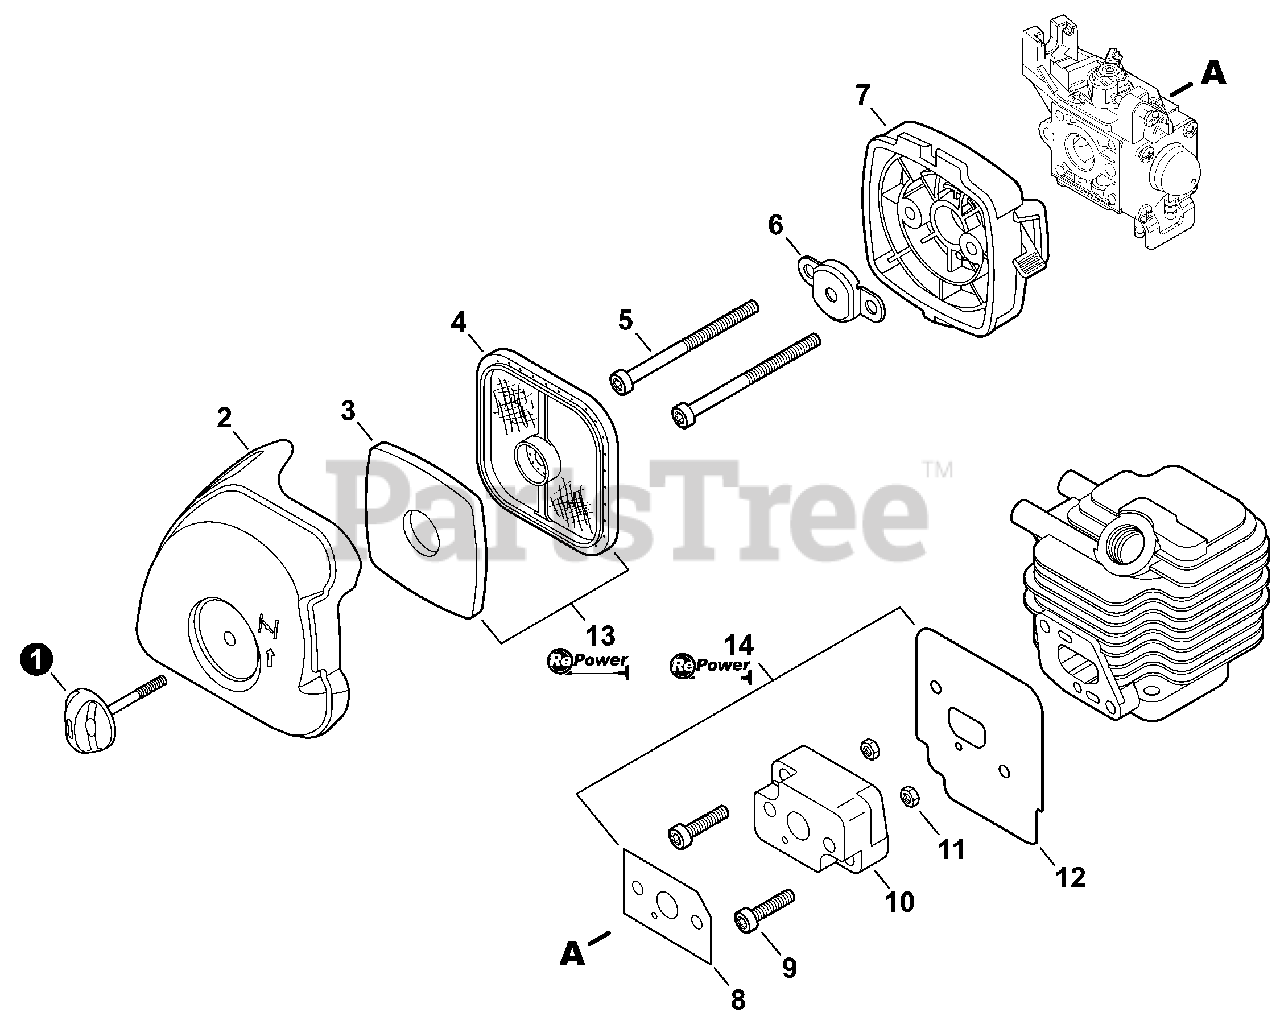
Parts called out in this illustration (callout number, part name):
1	THUMBSCREW
2	COVER, AIR FILTER
3	PRE-FILTER, FOAM
4	FILTER, AIR - DOUBLE LAYER
5	BOLT, TORX 5×65
6	PLATE, PREVENT
7	CASE, AIR FILTER
8	GASKET, INTAKE
9	BOLT, TORX 5×20
10	INSULATOR, INTAKE
11	NUT M5
12	HEAT SHIELD, INTAKE
13	TUNE-UP KIT - REPOWER
14	GASKET KIT
